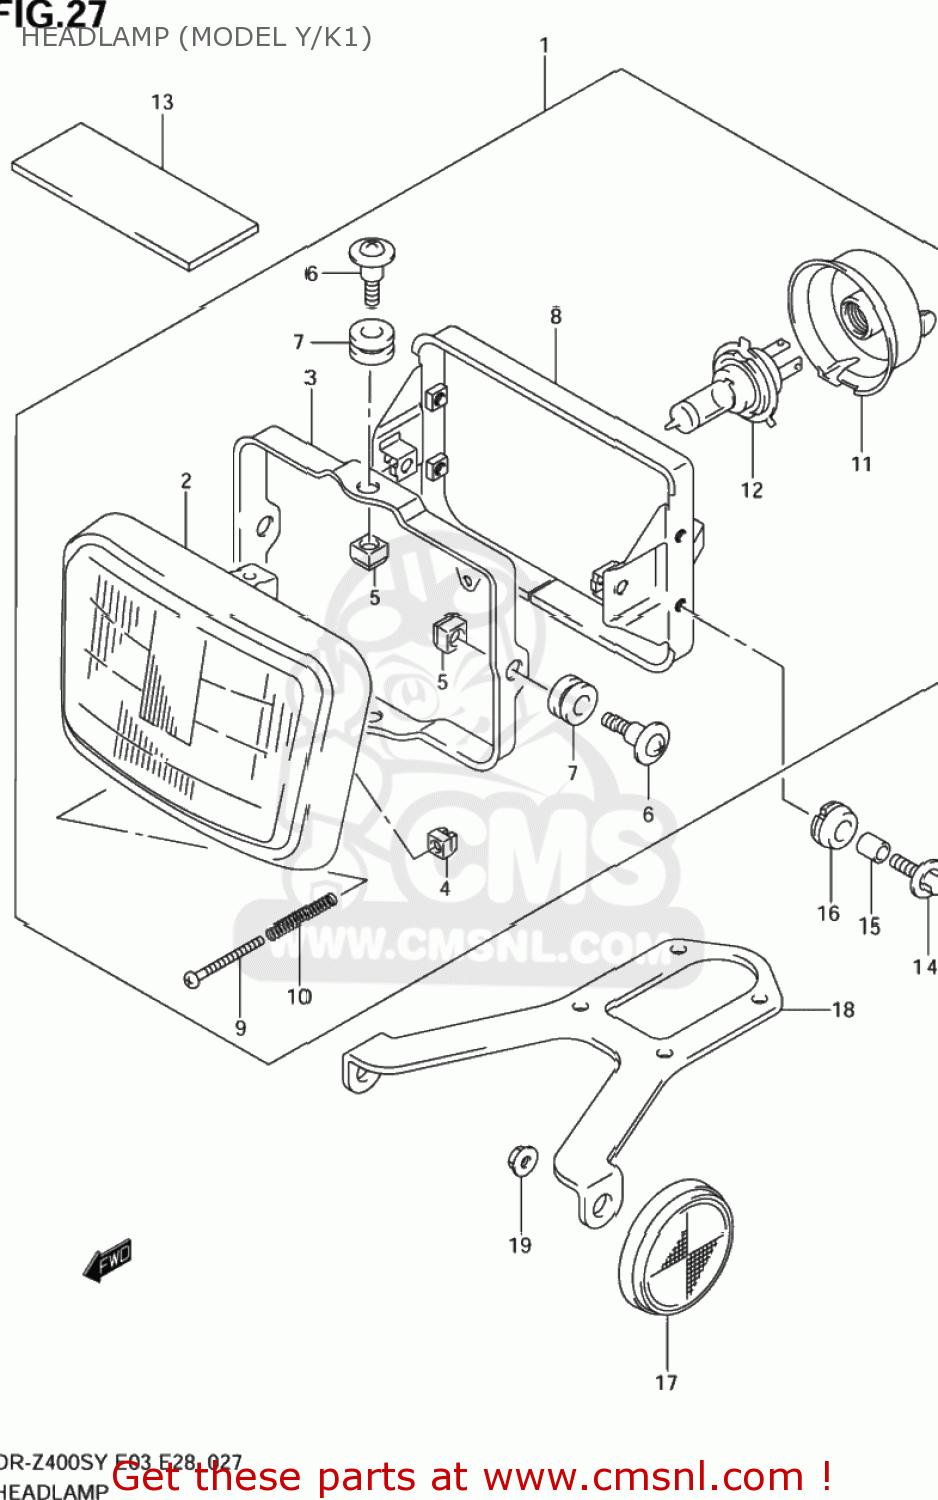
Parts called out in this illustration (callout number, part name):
1	HEADLAMP ASSY
2	UNIT ASSY
3	RING,MOUNTING
4	NUT,ADJUSTING
5	NUT
6	SCREW,MOUNTING
7	CUSHION
8	HOUSING
9	SCREW,ADJUSTING
10	SPRING,ADJUSTING
11	COVER,SOCKET
12	BULB(12V60/55W,H4)
13	PROTECTOR,WIRING HARNESS
14	BOLT(6X20)
15	SPACER(6.5X10X10)
16	CUSHION
17	REFLECTOR,REFLEX FR
18	BRACKET,FR SIDE RR
19	NUT
